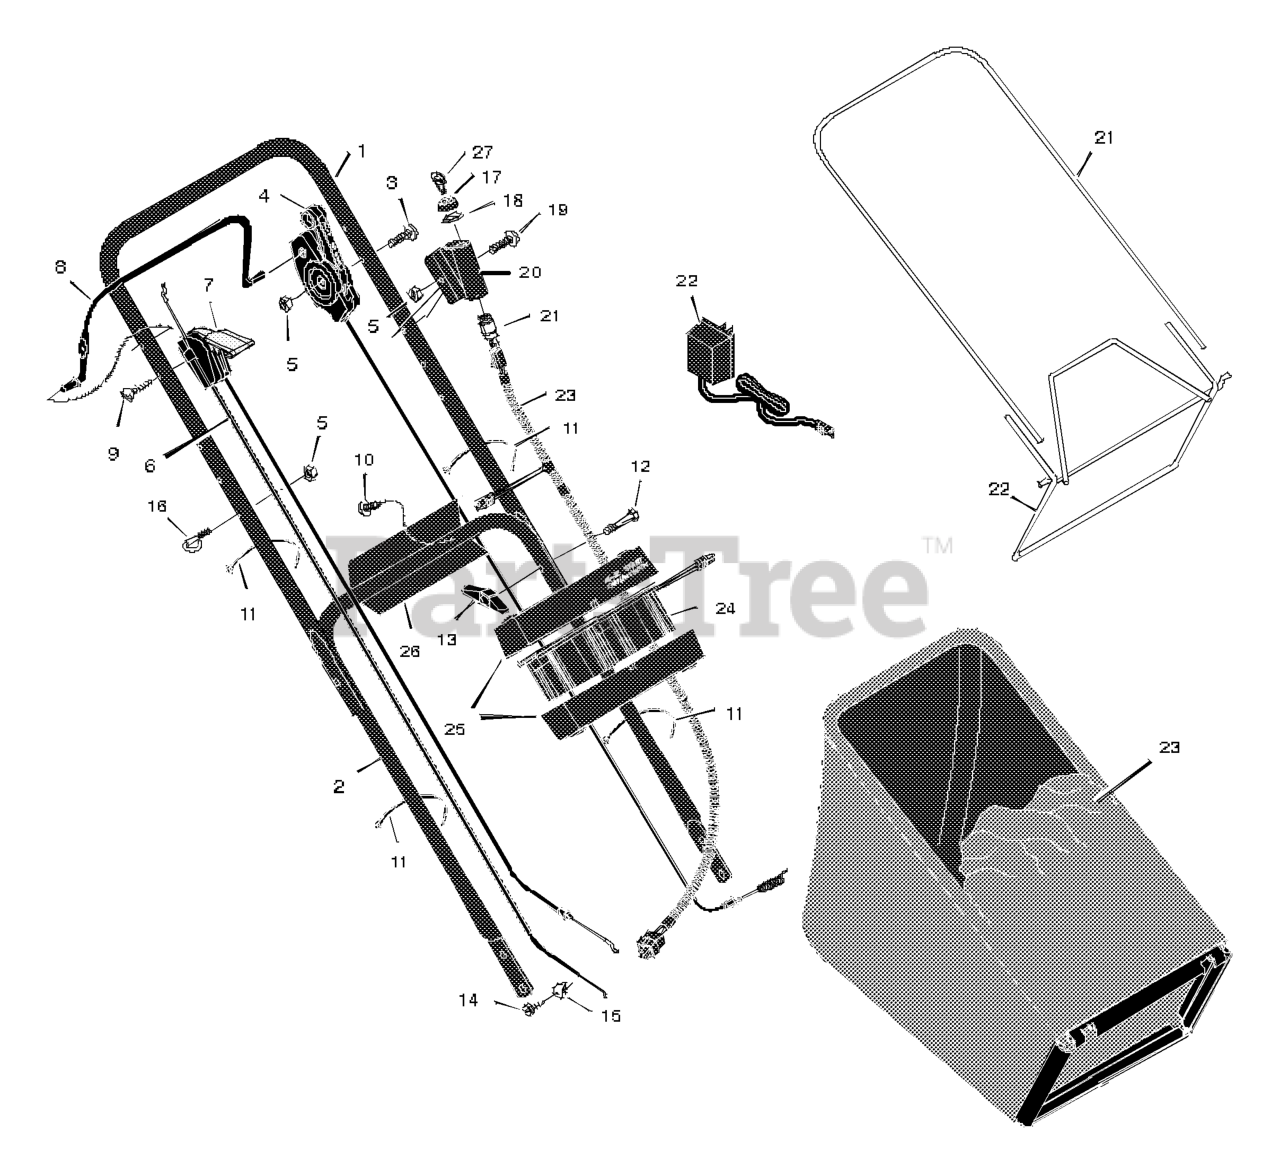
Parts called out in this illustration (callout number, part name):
1	Handle, Upper (Gray)
2	Handle, Lower (Gray)
4	Control, Drive
5	Locknut
6	Cable, Stop
7	Throttle Control
8	Engine Stop Lever
11	Fastener, Cable
13	Knob
16	GUIDE, ROPE
17	Cap
18	Nut
20	Cover, Ignition
21	Switch Ignition & Key
22	Charger, Battery
23	Harness, Wiring
24	Battery
25	Case, Battery
26	Bracket, Battery
27	Key, Ignition
28	Frame, Top
29	Frame Assembly
30	Bag, Cloth
